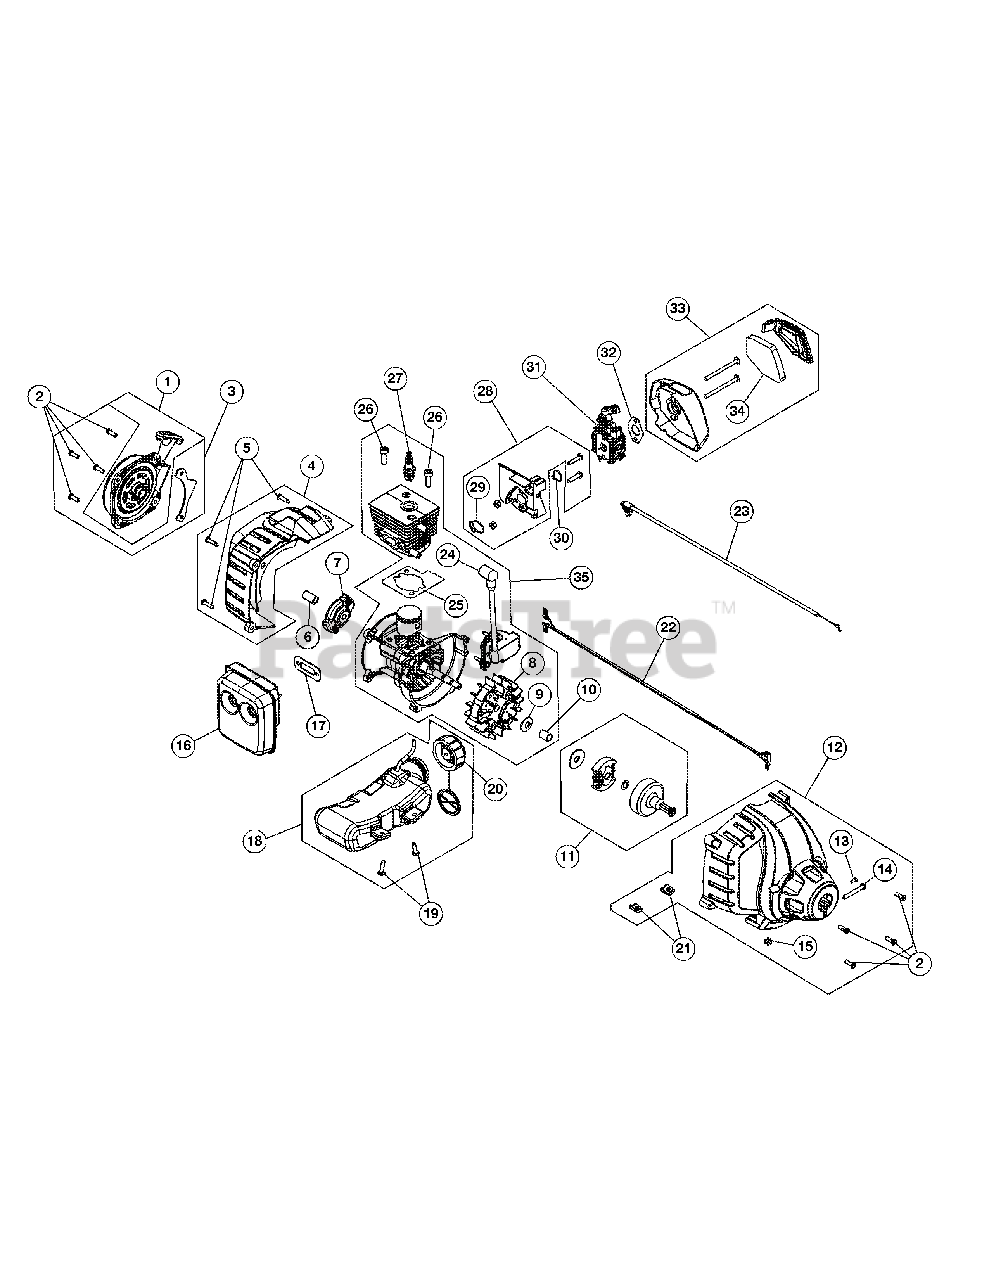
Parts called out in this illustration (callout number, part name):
1	Rear Cover Assembly (Incl. Ref No. 2 & 3)
2	Starter Screw
3	Starter Assembly Guard (Incl. Ref No. 2)
4	Rear Engine Cover (Incl. Ref No. 5)
5	Cover Screw
6	Adapter
7	Pawl Assembly
8	Flywheel Assembly
9	Washer
10	Spacer
11	Clutch Assembly
12	Clutch Cover Assembly (Incl. Ref No. 2, 13-15 & 21)
13	Anti-Rotation Screw
14	Clamp Screw
15	Clamp Nut
16	Muffler Assembly
17	Muffler Gasket
18	Fuel Tank Assembly (Incl. Ref No. 19 & 20)
19	Tank Screw
20	Fuel Cap
21	U-Shaped Nut
22	Lead Wires
23	Throttle Cable
24	Module Assembly
25	Cylinder Gasket
26	Cylinder Bolt
27	Spark Plug
28	Insulator Assembly (Incl. Ref No. 29)
29	Insulator O-Ring
30	Carburetor O-Ring
31	Carburetor
32	Carburetor Gasket
33	Aircleaner Assembly (Incl. Ref No. 34)
34	Aircleaner Filter
35	Short Block Assembly
